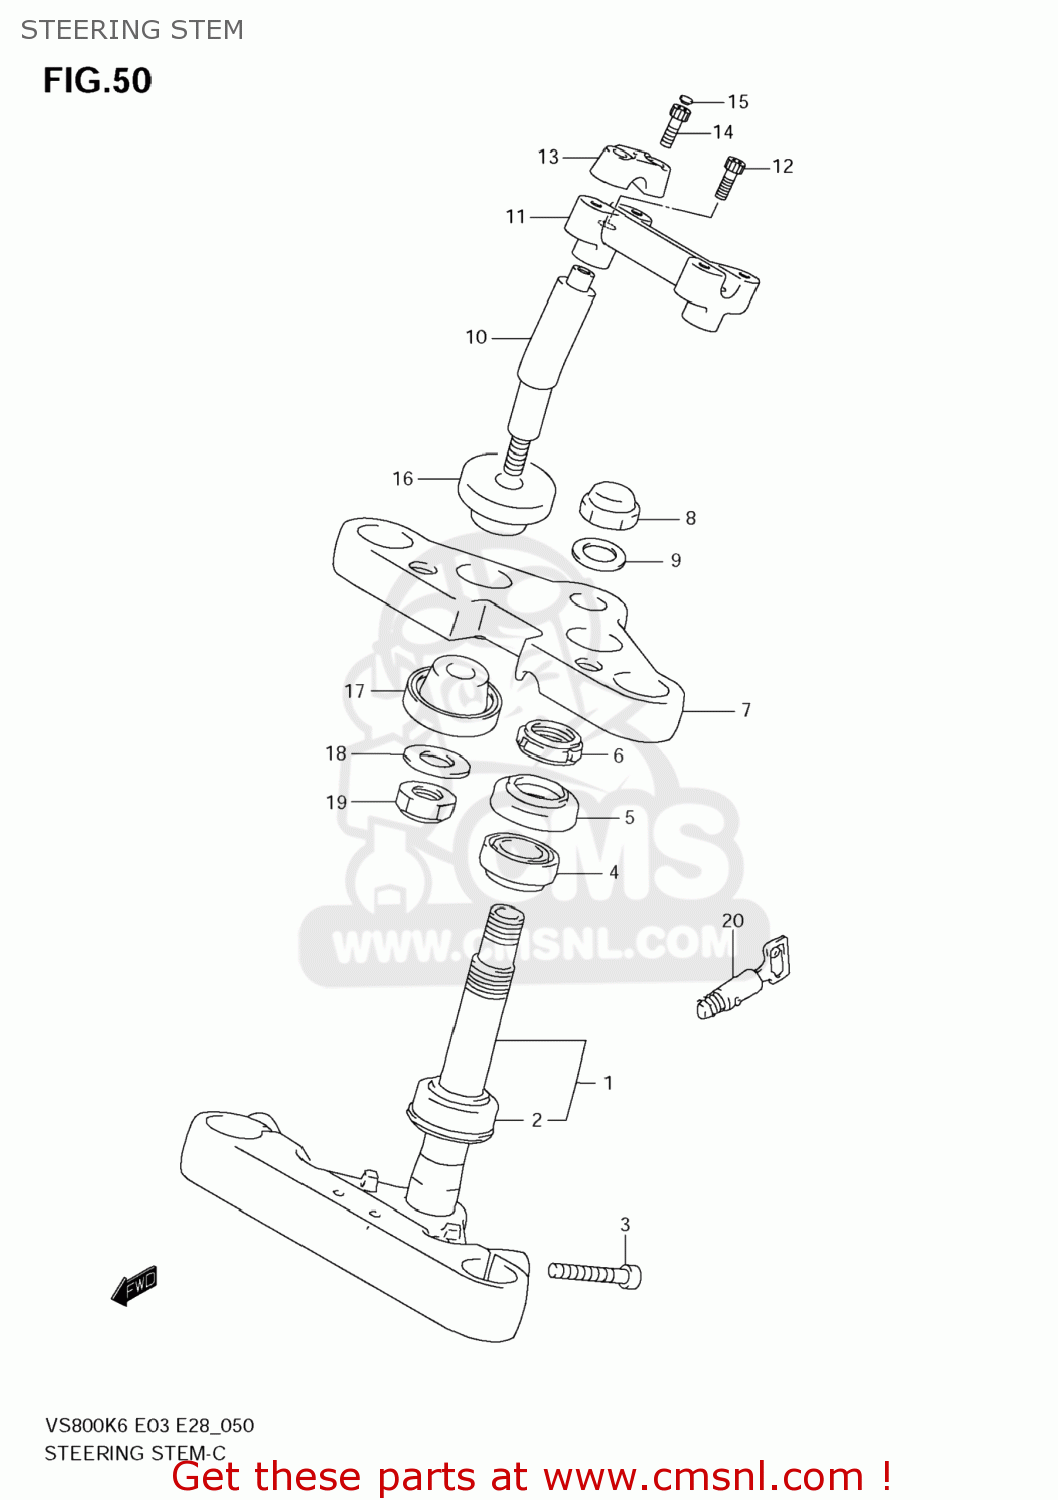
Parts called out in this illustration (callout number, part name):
1	STEM,STEERING
2	BEARING(30X55X17)
3	BOLT
4	BEARING(25X47X15)
5	SEAL,STEERING UPR DUST
6	NUT,STEERING STEM(25X44X10)
7	BRACKET,UPR
8	NUT,CAP
9	WASHER(22.5X32X1.6)
10	STAY,HANDLE
11	HOLDER,HANDLE LWR
12	BOLT
13	HOLDER,HANDLE UPR
14	BOLT
15	CAP(OD:14.5)
16	DAMPER,RUBBER
17	CUSHION,RUBBER UNDER
18	WASHER
19	NUT
20	LOCK SET,STEERING
